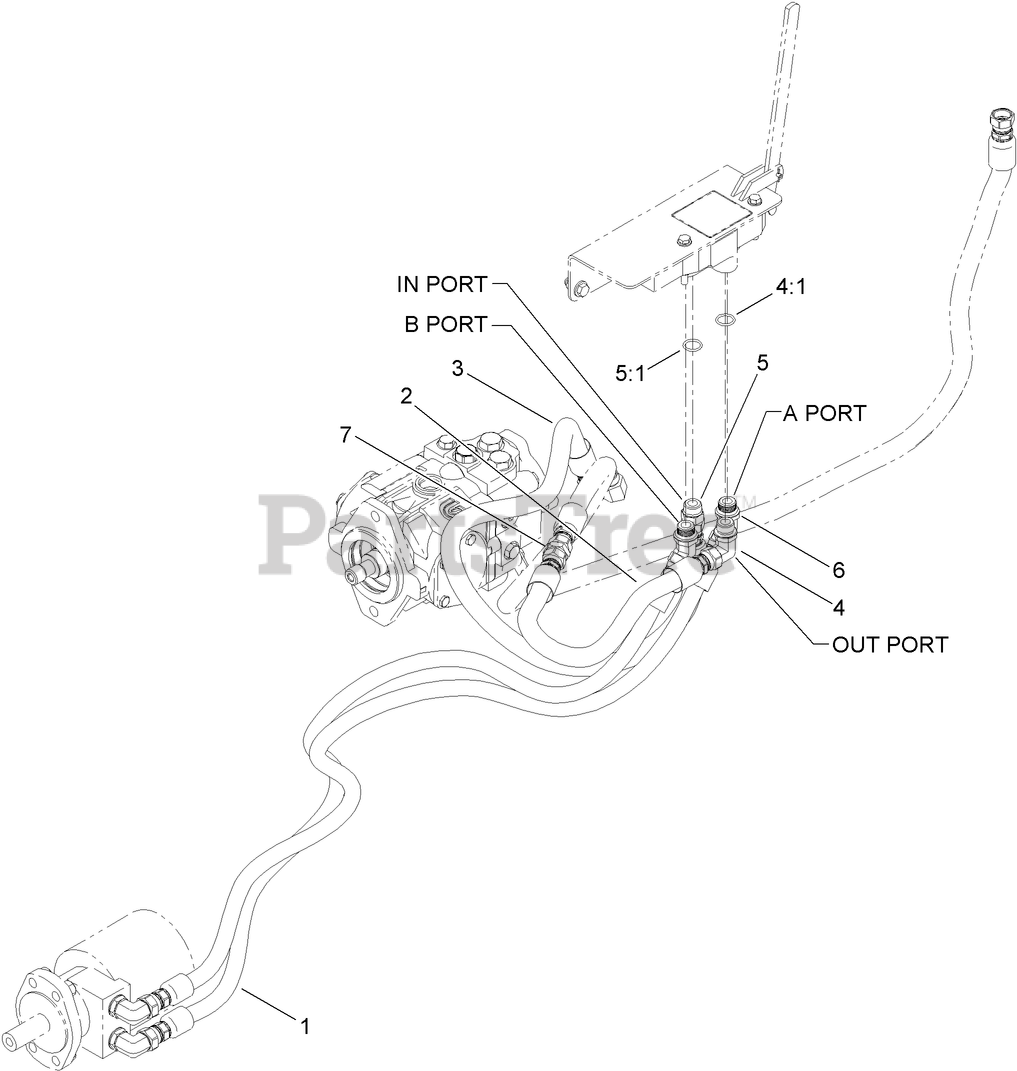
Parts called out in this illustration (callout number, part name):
1	HOSE ASM
2	HYD HOSE ASM
3	HOSE ASM
4	FITTING-ELBOW, 90 DEG
4:1	O-RING
5	FITTING-STRAIGHT
5:1	O-RING
6	FITTING-ELBOW, 45 DEG
7	FITTING-UNION
